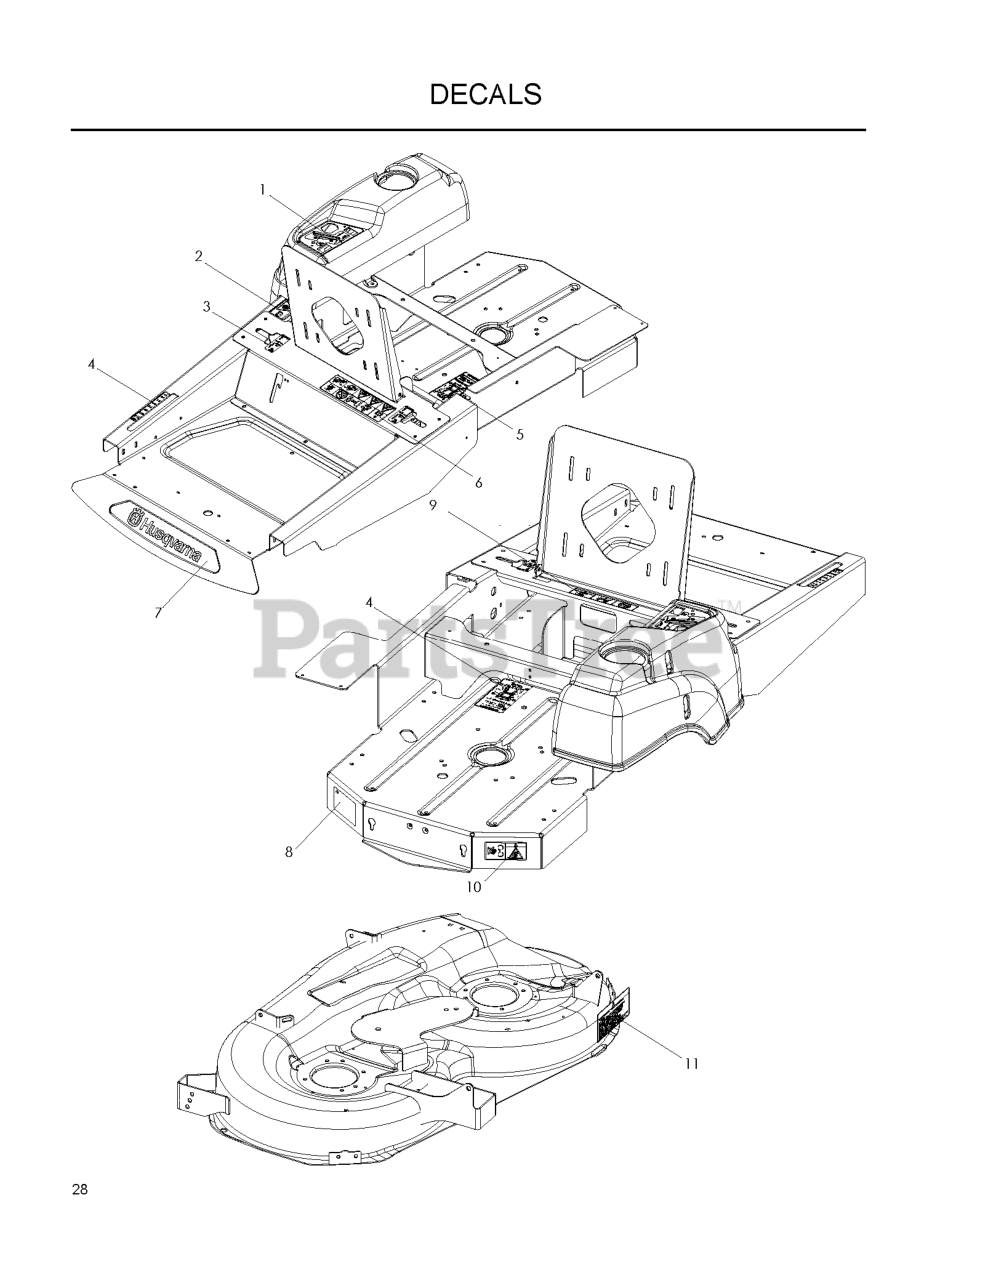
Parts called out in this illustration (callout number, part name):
1	DECAL, IGNITION CONSOLE
2	DECAL, EXITING MOWER
3	DECAL, HEIGHT, CE
4	DECAL, MOTION CONTROL
5	DECAL, SERVICE
6	DECAL, WARNING
7	DECAL, HUSQ 12" BLUE
8	DECAL, DO NOT TOW
9	EURO DECAL-BATTERY WARNIN6
10	DECAL, BELT DRIVE
11	DECAL, DISCHARGE, MULTILINGUAL
